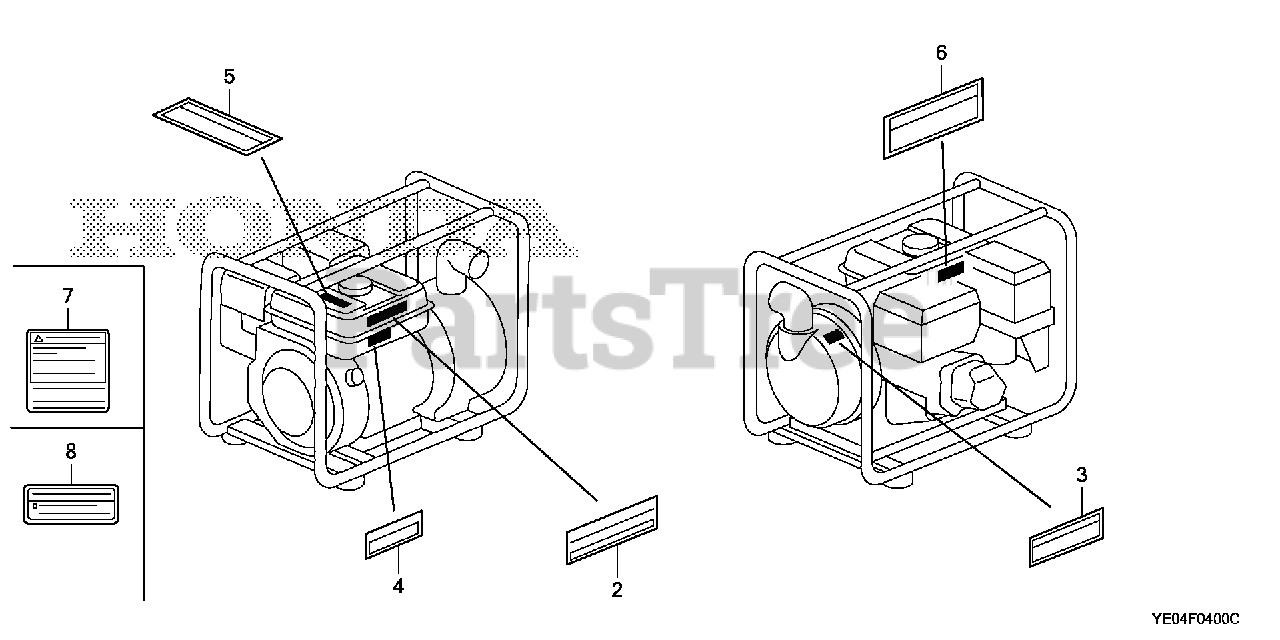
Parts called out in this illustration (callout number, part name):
2	MARK (WMP20X)
3	LABEL, WARNING
4	MARK, OIL ALERT (ENGLISH)
5	LABEL, SPARK WARNING
